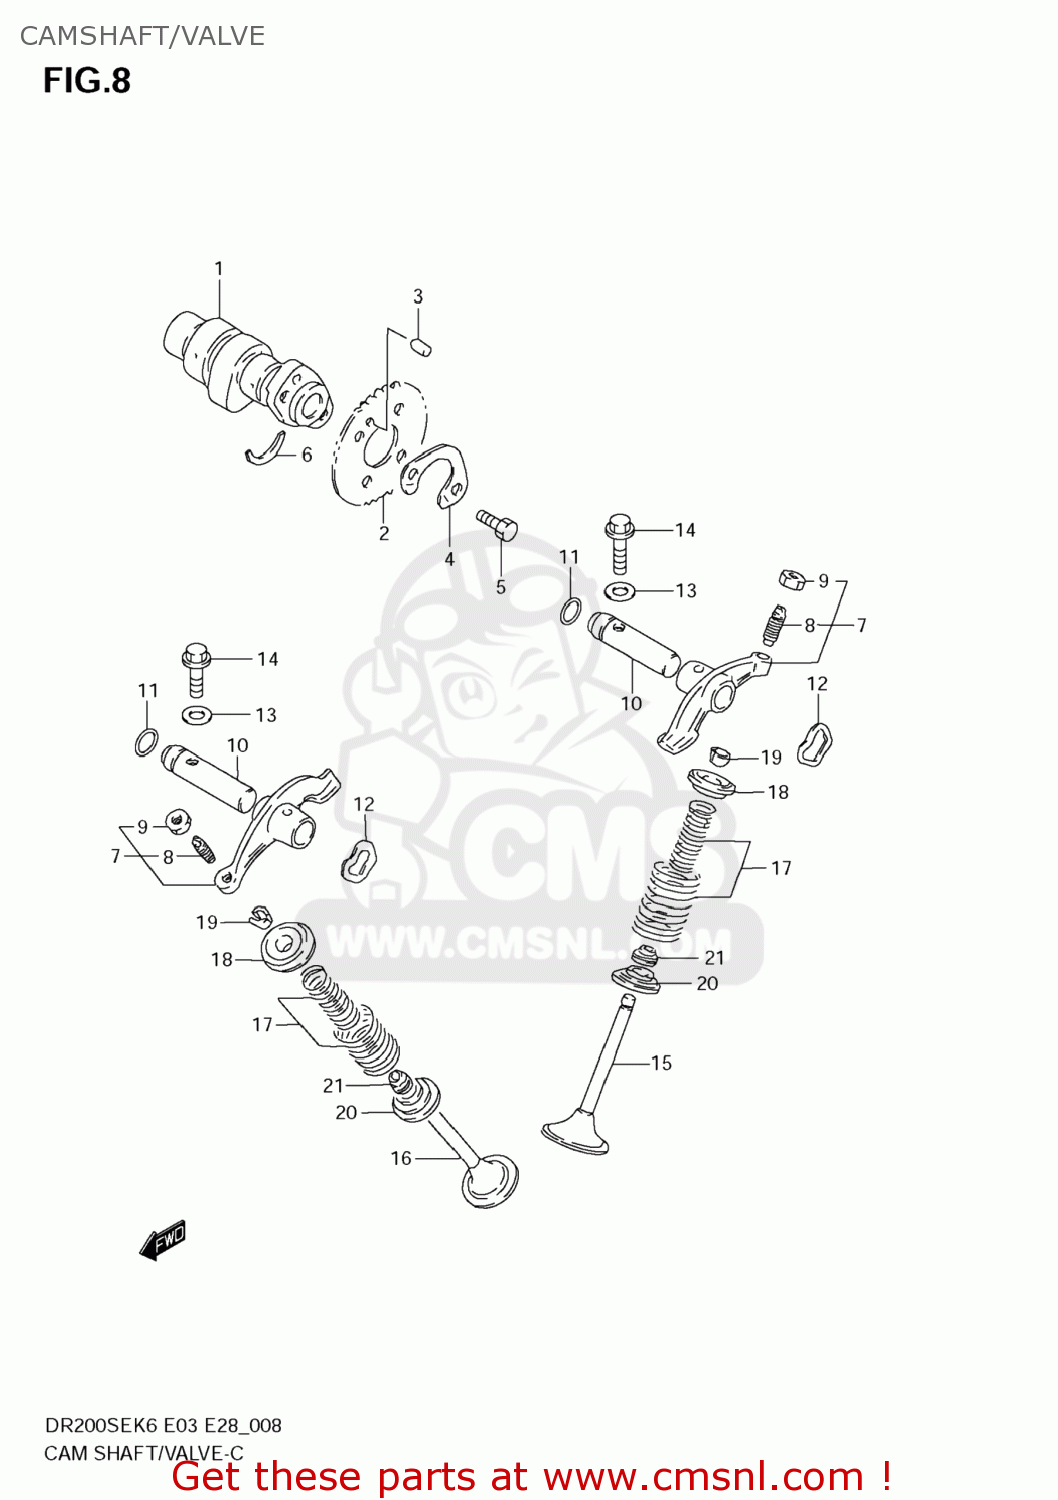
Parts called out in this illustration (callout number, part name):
1	CAMSHAFT
2	SPROCKET,CAMSHAFT
3	PIN(5X8)
4	WASHER,SPROCKET
5	BOLT(6X10.5)
6	C RING
7	ARM,VALVE ROCKER
8	SCREW,TAPPET ADJUSTING
9	NUT,ADJUSTING SCREW
10	SHAFT,VALVE ROCKET
11	O RING(D:1.9,ID:8.6)
12	WASHER
13	GASKET(5.8X13X1.2) (NAS)
14	SCREW
15	VALVE,INTAKE
16	VALVE,EXHAUST
17	SPRING SET,VALVE
18	RETAINER,VALVE SPRING
19	COTTER,VALVE
20	SEAT,VALVE SPRING
21	SEAL,OIL(5.5X11X8.2)
